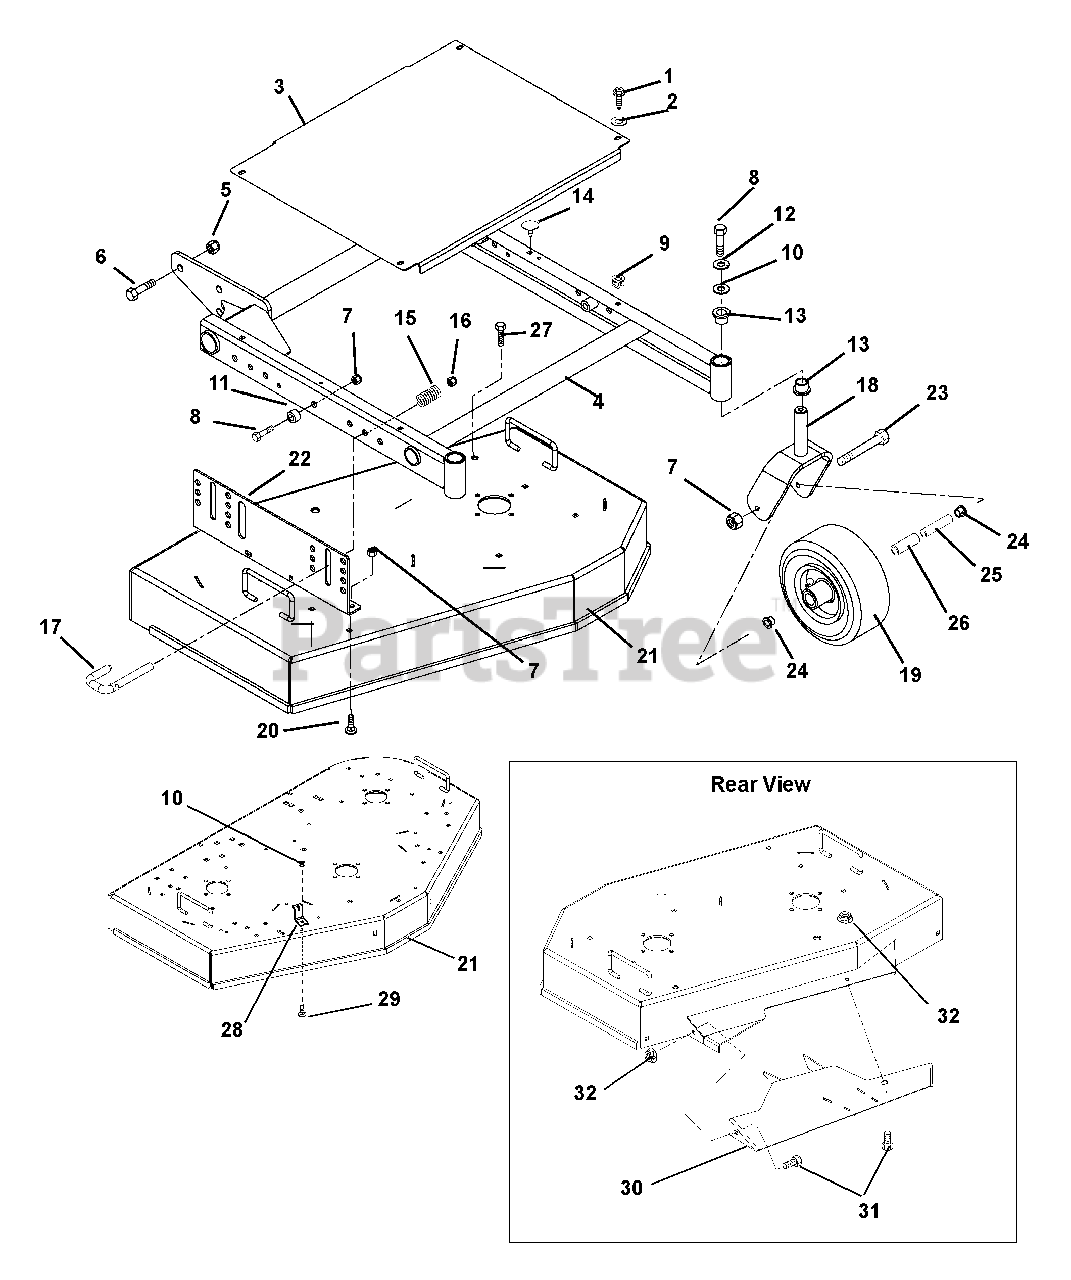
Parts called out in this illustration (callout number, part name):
1	@SCR-TAP .25-20X.50 HWH TR YWZ
2	@WSHR-FL-STL.281X.62X.065 YWZC
3	COVER - BELT - PRO - 32"
3	COVER - BELT - PRO MOWER
3	COVER - BELT - PRO - 44"
4	WMT - MOWER FRAME - 32"
4	COVER - BELT - PRO MOWER
4	WMT - MOWER FRAME - 44"
5	@NUT-LK-NYL .625-11 YWZC
6	@BLT-HEX .62-11X1.50 GR5 YWZC
7	@NUT-LK-TOP-FLG .38-16 YWZC
8	@BLT-HEX .38-16X1.25 GR5 YWZC
9	GRMT,PLASTIC
10	WSHR-FL-STL .380X1.50X.125YWZC
11	BSHG-SLV .391X.688X.52 PM
12	@WSHR-LK .38X.094 REG YWZC
13	BSHG-FLG 1.00X1.25X1.50X1.50EP
14	BUMPER GROMMET
15	SPRG, COMP .058X.65X2.13 WLD15
16	@NUT-LK-CTR .50-13 YWZC
17	PIN - LATCH
18	WMT - CASTER FORK
19	WHEEL 9 X 3.50 SEMI-PNEUMATIC
20	@BLT-RDHDSQNK .38-16X1.00 G5YZ
21	KIT-32" REAR DIS DECK W/DECALS
21	KIT-36" REAR DIS DECK W/DECALS
21	KIT-44" REAR DIS DECK W/DECALS
22	KIT-MOWER SIDE SUPT BRKT-RH&LH
23	BLT-HEX .38-16X5.50 YWZC
24	RTNR-BEARING-PRO
25	BEARING .625 X .380 X 4.08
26	BEARING, ROLLER--PRO
27	@BLT-HEX .38-16X1.00 GR5 YWZC
28	ANCHOR, SPRING (RED)
29	@BLT-RDHDSQNK .38-16X.75 G5YZ
30	WMT-36" DEFLECT EXT-REAR DISCH
30	WMT-32" DEFLECT EXT-REAR DISCH
31	@BLT-HEX .31-18X.75 GR5 YWZC
32	@NUT-LK-TOP-FLG .31-18 YWZC
